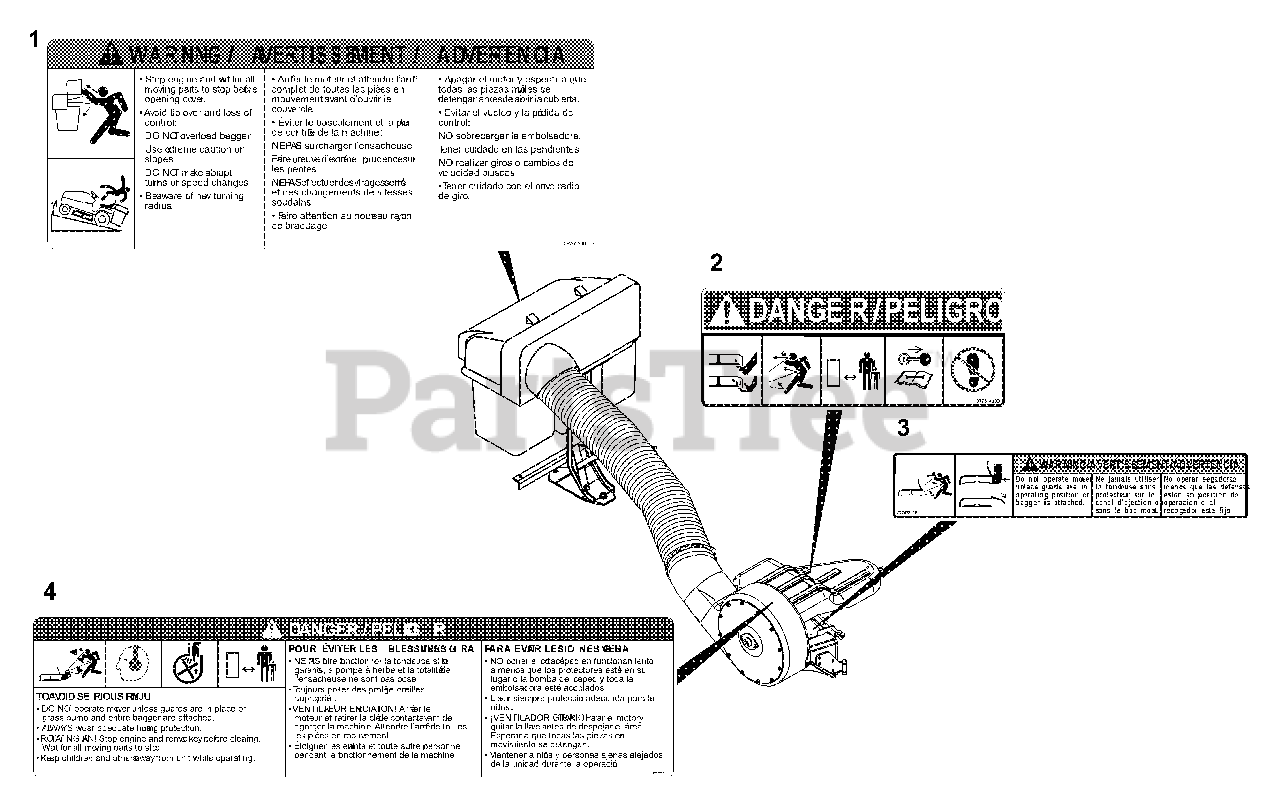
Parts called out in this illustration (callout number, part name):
1	Decal-Warning, Bagger Cover
2	Decal, Mower Pan Head Danger
3	Decal, Warning
4	Decal-Caution, Grass Pump
